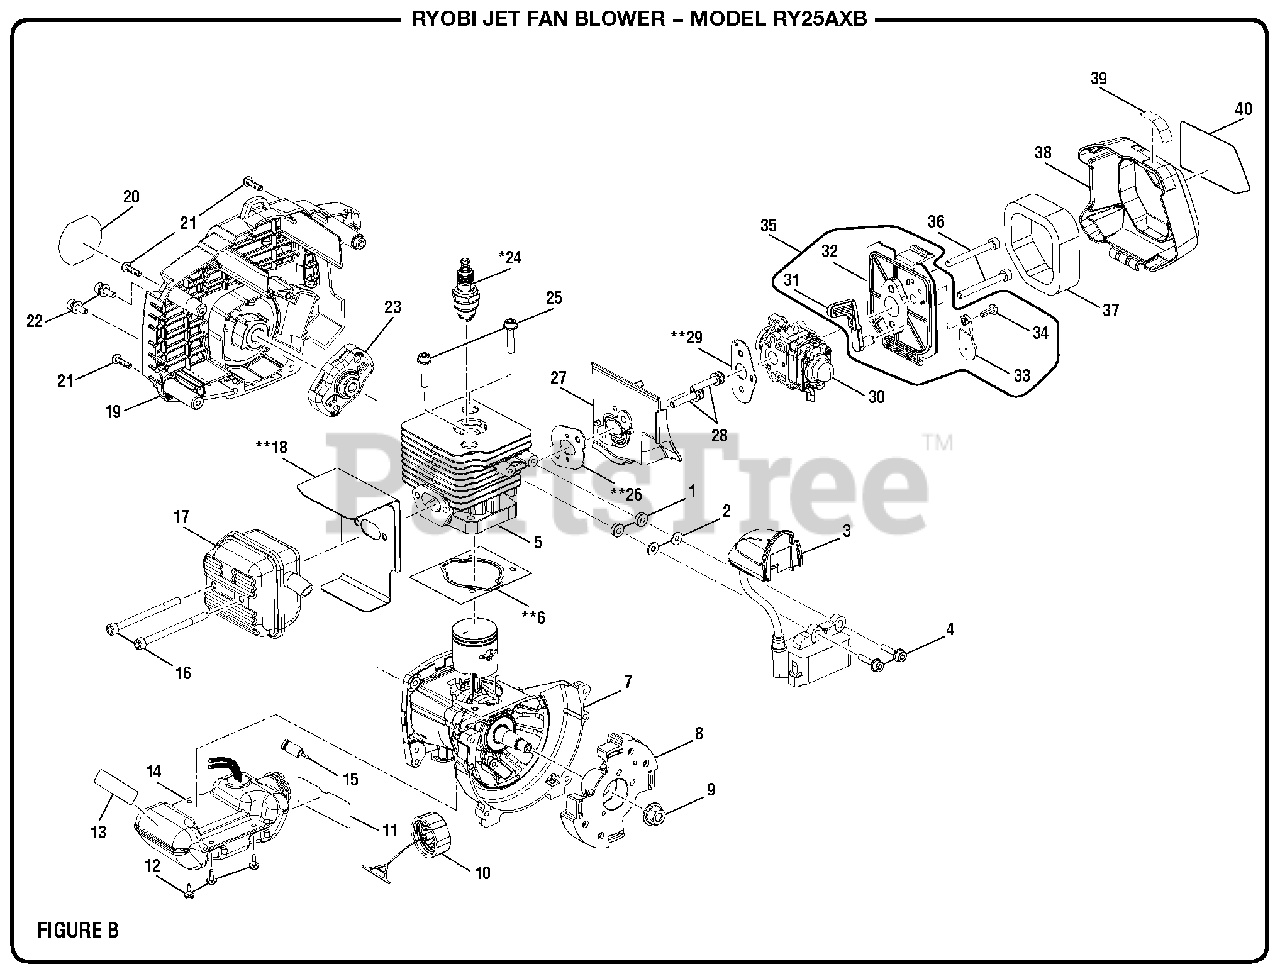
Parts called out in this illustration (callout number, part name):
2	Washer (ID4.2 x OD10 x 1t)
3	Ignition Module
4	Screw (M4 x 19 mm, T20 Torx Pan Hd. S.T.)
6	Gasket
7	Crankcase Assembly
9	Flange Nut (M8, Flywheel)
10	Fuel Cap Assembly
11	Fuel Mixture Label
12	Shoulder Screw (M4 x 14 mm, T25 Torx Truss Hd. S.T.)
13	Combustion Warning Label
14	Fuel Tank w/Cap Assembly
15	Fuel Filter
16	Cap Screw (M5 x 65 mm, T25 Torx Soc. Hd.)
17	Muffler Assembly
18	Muffler Gasket
19	Rear Housing and Starter Assembly
20	Logo Label (Rear)
21	Screw (M4 x 18 mm, T20 Torx Pan Hd. S.T.)
22	Cap Screw w/Washer (M5 x 16 mm, T25 Torx Soc. Hd.)
23	Starter Cup
24	Spark Plug (L7RTC)
25	Screw (M5 x 22 mm, T25 Torx Soc. Hd.)
26	Gasket (Heat Dam)
28	Screw w/Washers (M5 x 30 mm, T25 Torx Pan Hd.)
29	Gasket (Carburetor)
30	Carburetor Assembly
31	Choke Lever
32	Air Box Base
33	Choke Plate
34	Screw (M4 x 12 mm, T20 Torx Pan Hd.)
35	Airbox Assembly
36	Cap Screw (M5 x 45, T25 Torx Soc. Hd.)
37	Air Filter
38	Air Box Cover
39	Choke Label
40	Starting Instructions Label
